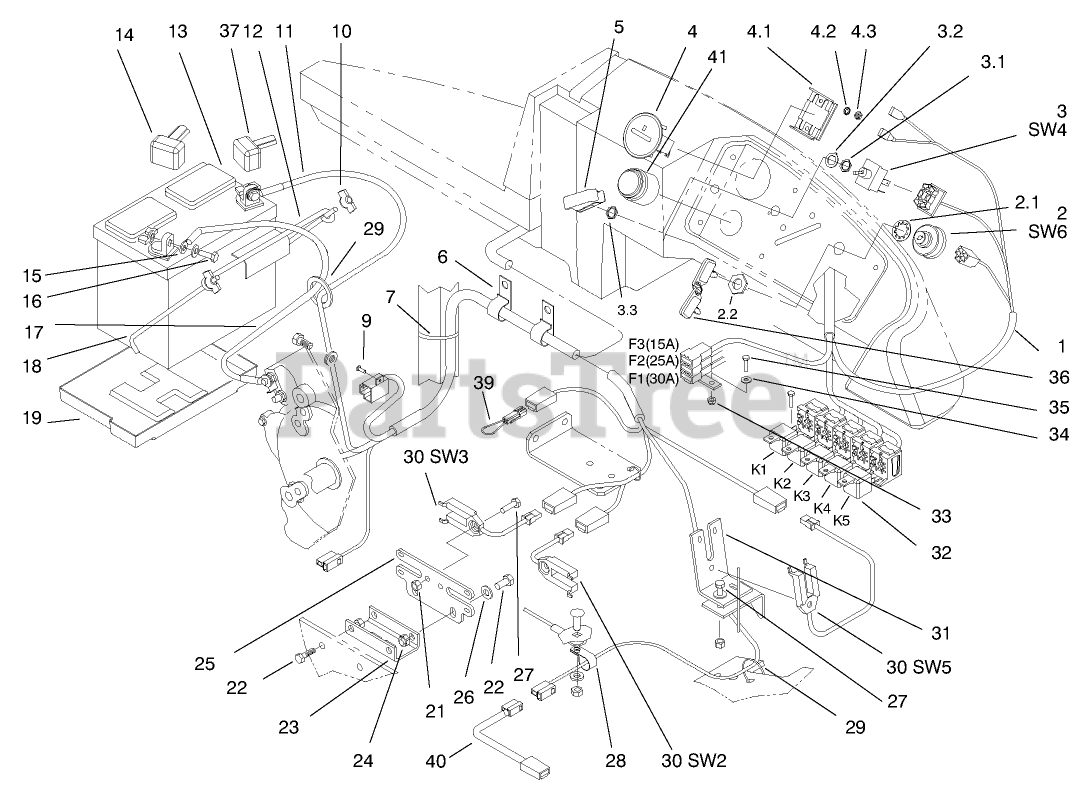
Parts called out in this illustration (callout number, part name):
1	HARNESS
2	IGNITION SWITCH ASM
2:2	WASHER-LOCK
3	SWITCH-TOGGLE, SEALED
3:1	NUT-HEX, SPECIAL
3:2	TAB-WASHER
4	Hourmeter
4:1	CLAMP-HOUR METER
4:2	WASHER-LOCK
4:3	NUT-HEX
5	COVER-PTO SWITCH
6	CLAMP-J
7	TIE-CABLE
9	SCREW-TAP
10	NUT-WING
11	WIRE ASM (NEGATIVE)
12	HOLDDOWN-BATTERY
13	BATTERY
13	ASM-BATTERY W/DECALS
14	BOOT-TERMINAL
15	WASHER-FLAT
16	SCREW-HH
17	WIRE ASM
18	RETAINER-BATTERY
19	TRAY-BATTERY
21	NUT-LOCK, NI
22	SCREW-HH
23	CHANNEL-MOUNT, SWITCH
24	NUT-LOCK, NI
25	PLATE-MOUNT, SWITCH
26	WASHER-PLAIN
27	SCREW-HH
28	CLAMP-R
29	TIE-CABLE
30	SWITCH-INTERRUPTER
31	ANGLE - MOUNT,SWITCH
32	RELAY
33	NUT-LOCK, NI
34	WASHER-FLAT
35	SCREW-HWH
36	KEY-IGNITION
39	JUMPER
40	HARNESS - SEAT ADAPTER
